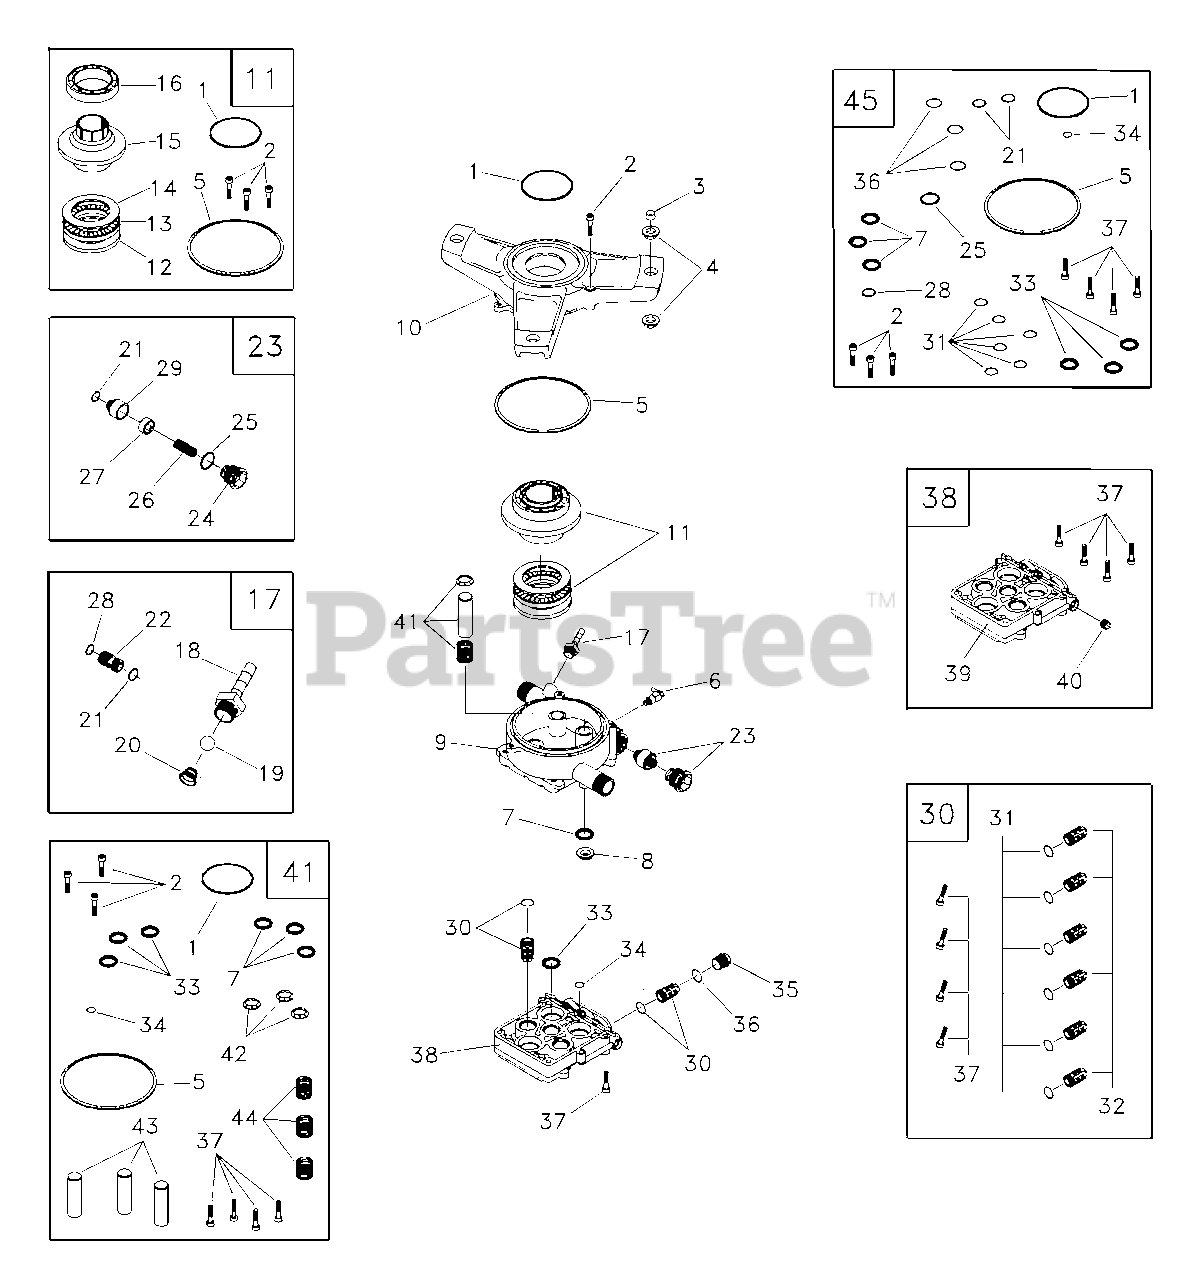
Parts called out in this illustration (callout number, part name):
1	SEAL, Engine Donut
2	CAPSCREW, Socket Head
3	SLEEVE, Grommet Spacer
4	BUSHING, Rubber Mount
5	O-RING, Housing Seal
6	THERMAL RELIEF, GPW-EG
7	SEAL, Oil Piston
9	HOUSING, Piston
10	ADAPTER, Engine
11	KIT, AXIAL CAM SERV
12	WASHER, Brg.
13	ASSY, Brg. Cage
14	WASHER, Brg.
15	CAM, Axial
16	BEARING, Ball
17	KIT, CHEM INJECT
18	FITTING, Chem Inject
19	BALL, Chem Inject
20	SPRING, Chem Inject
21	O-RING, Venturi & Seat, Black
22	VENTURI, Chem Inject
24	CAP, Unloader
25	O-RING, Unloader Cap
26	SPRING, Unloader
27	ASSY, Piston, Unloader
28	O-RING, Venturi, Yellow
29	SEAT, Unloader
30	KIT, CHECK VALVES
31	O-RING, Check Valve
32	ASSY, Check Valve
33	SEAL, Double-Lip
34	O-RING, Hi-Pressure Transfer
34	O-RING, High Pressure Transfer
35	CAP, Outlet Check Valve
36	O-RING, Outlet CV Cap
37	CAPSCREW, Socket Head
38	KIT, HEAD CASTING SFG
39	HEAD, Pump
40	PLUG, W/VIRB
41	KIT, PISTON & SPRING
42	RETAINER, Piston Spring
43	PISTON
44	SPRING, Piston Return
45	KIT, O-RING/SEAL SERV
